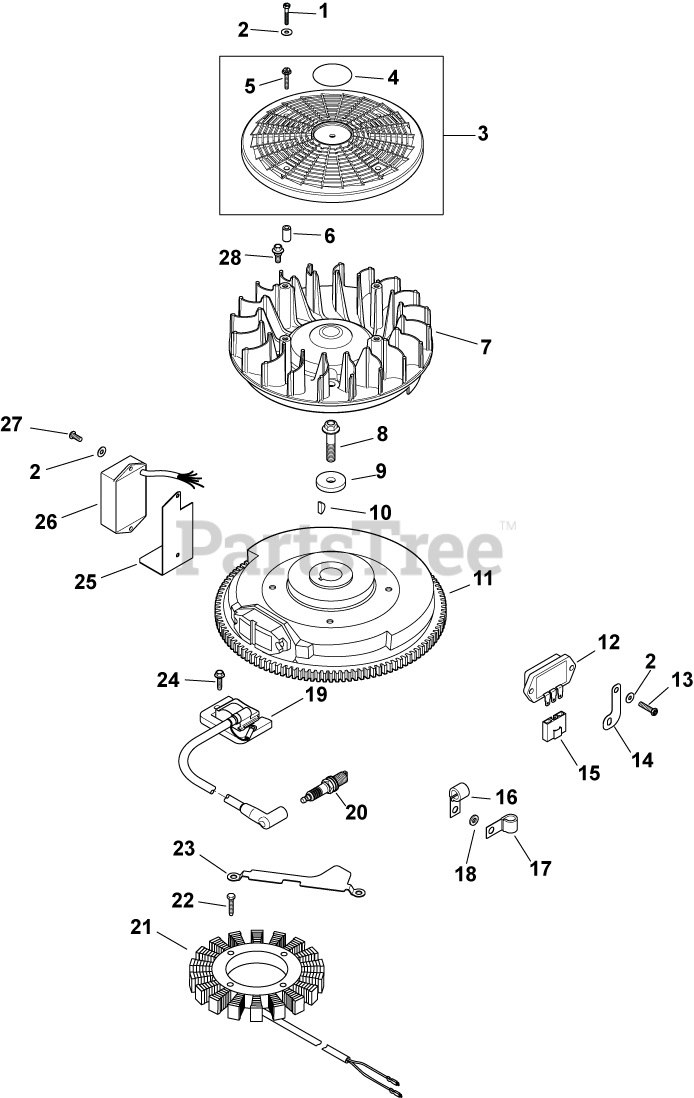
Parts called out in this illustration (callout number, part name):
1	SCREW, SLT HD CAP M4X0.7X25
2	WASHER, FLAT 3/16"
3	KIT, GRASS SCREEN
4	DECAL, GRASS SCREEN USE 24 113 499-S
5	SCREW, FLG SEMS M4X.7X25
6	SPACER - DISCONTINUED
7	FAN (DOMED)-USE 24 157 17-S
8	SCREW, FLG M10X1.5X45 - (#25086361S)
9	WASHER, FLAT 13/32"
10	KEY, 3/16" X 5/8"
11	FLYWHEEL ASSEMBLY - USE 24 025 14-S
12	REG/RECT-15 AMP (KM)-USE 41 403 10-S
13	SCREW, PHL HD #11-16X7/8"
14	BRACKET, GROUND STRAP USE 24 518 12-S
15	CONNECTOR, BODY (KM)-USE 25 155 41-S
16	CLIP, CABLE
18	WASHER, FLAT 1/4" (O.D. 1/2")
19	MODULE, IGNITION
20	PLUG, SPARK (PRO SERIES)
21	KIT, 15 / 20 AMP STATOR
22	SCREW, M5X0.8X25 - (#25086402S)
23	BRACKET, STATOR WIRE-USE 24 126 139-S
24	SCREW, FLG THD FRM M5X.8X20-(#25086399S)
25	BAFFLE, HEAT SHIELD - DISCONTINUED
26	MODULE, SPEED ADVANCE
27	SCREW, THD FRM M4X0.7X10
28	BOLT, SHOULDER
